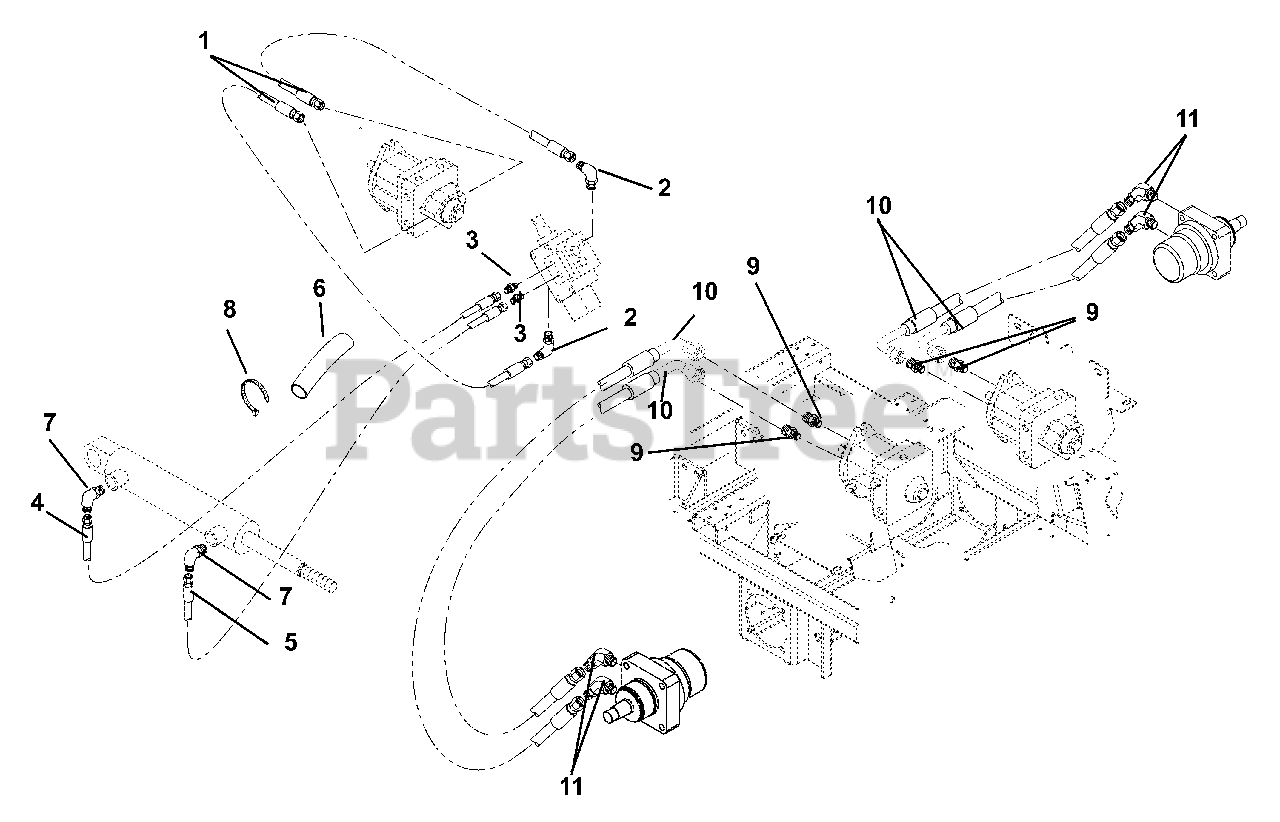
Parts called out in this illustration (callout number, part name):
1	HOSE,HYD.25-22-2K F04F9-F06FO
2	FTG, HYD ELBOW M6F-M8O
3	FITTING, HYD (4-6 F5OLO)
4	HOSE,HYD.25-42-2K F04F0-F04F4
5	HOSE,HYD .25-47-2K F04F0-F04F4
6	SLEEVE, PROTECTIVE
7	FITTING, HYD (4 C5OLO)
8	CABLE TIE LG 5-1/2
9	ADPTR,FACE SEAL 8X8 1/2 O-RING
10	HOSE,HYD .50-17-2K F08F0-F08F9
11	FITTING, HYD (8-10 V5OLO)
